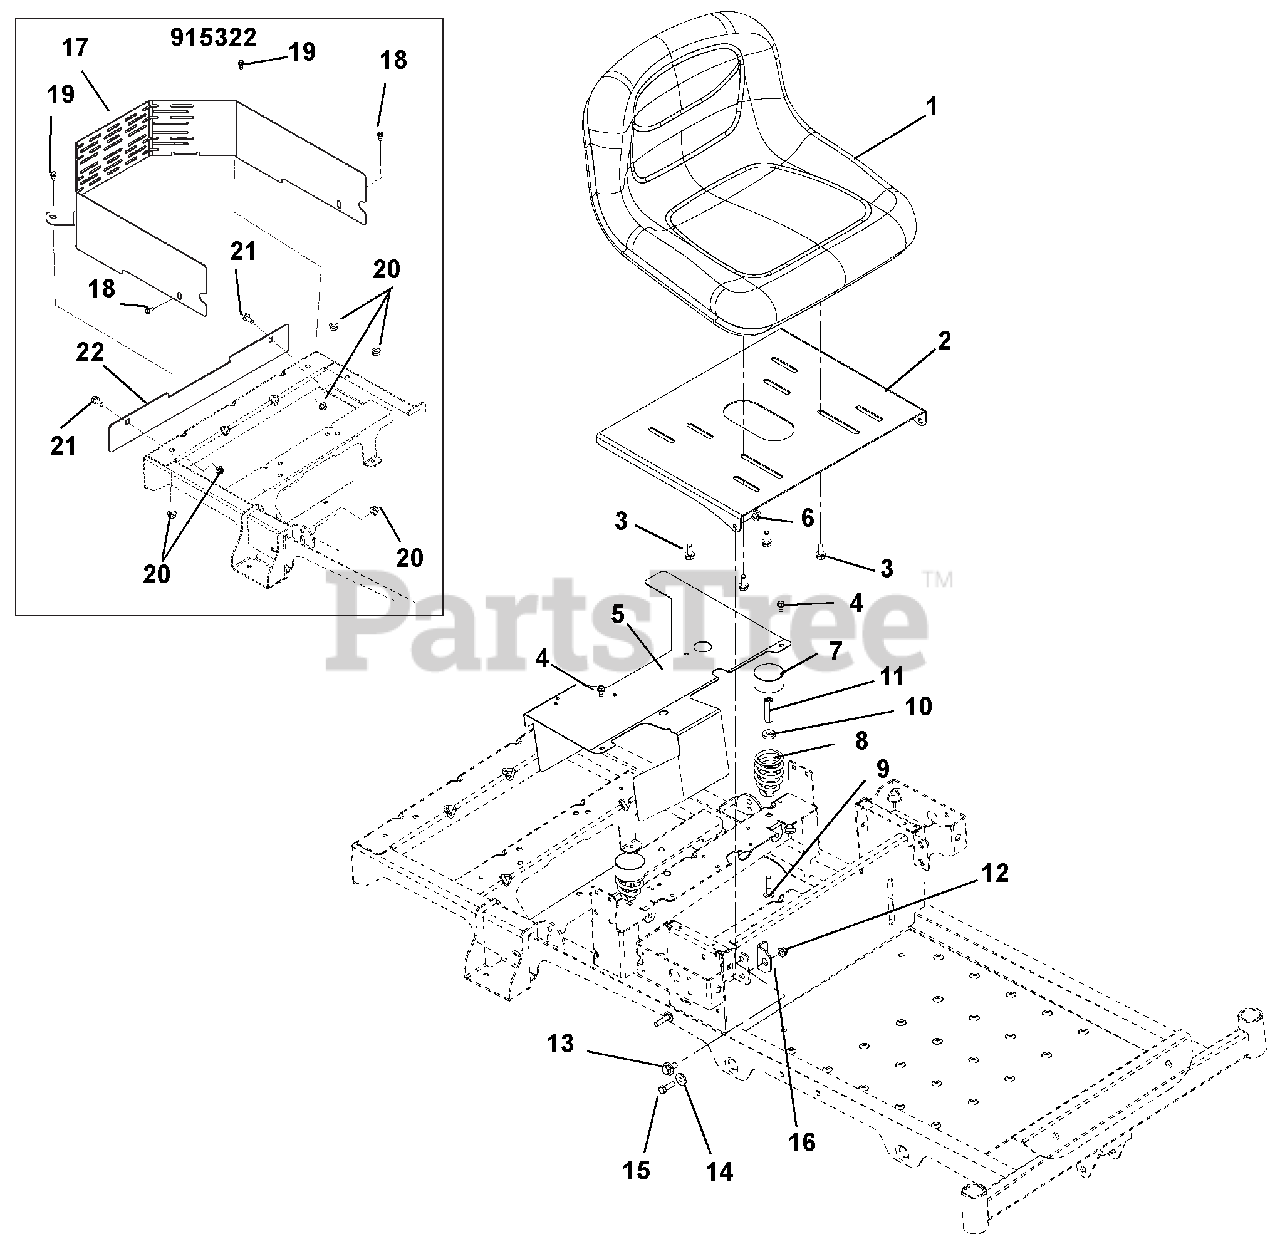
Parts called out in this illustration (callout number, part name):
1	SEAT-13" GREY
2	PLATE, SEAT
3	5/16-18X3/4 HX/W/HD WHIZ
4	@SCR-TAP .25-20X.50 HWH TR YWZ
5	COVER, ZOOM CE FAN
6	@NUT-LK-TOP-FLG .38-16 YWZC
7	HUB CAP
8	SPRING, SEAT
9	@BLT-RDHDSQNK .31-18X1.50 G5YZ
10	WSHR-FL-STL .328X.87X.179 YWZC
11	NUT, COUPLING 5/16-18 X 1 3/4
12	@NUT-LK-NYL-FLG .31-18 YWZC
13	BOLT-SHLDR .375-16X.150
14	BSHG, FLG .325X.499X.26X.88
15	@BLT-HEX .31-18X1.00 GR5 YWZC
16	BRKT, SEAT STOP
17	WALL, CE REACH-IN (ZOOM)
18	@BLT-HEX .38-16X.75 GR5 YWZC
19	@BLT-HEX .38-16X1.00 GR5 YWZC
20	NUT-LK-CTR-FLG .38-16 YWZC
21	@BLT-RDHDSQNK .38-16X.75 G5YZ
22	FLANGE, ZOOM MUFFLER (CE)
